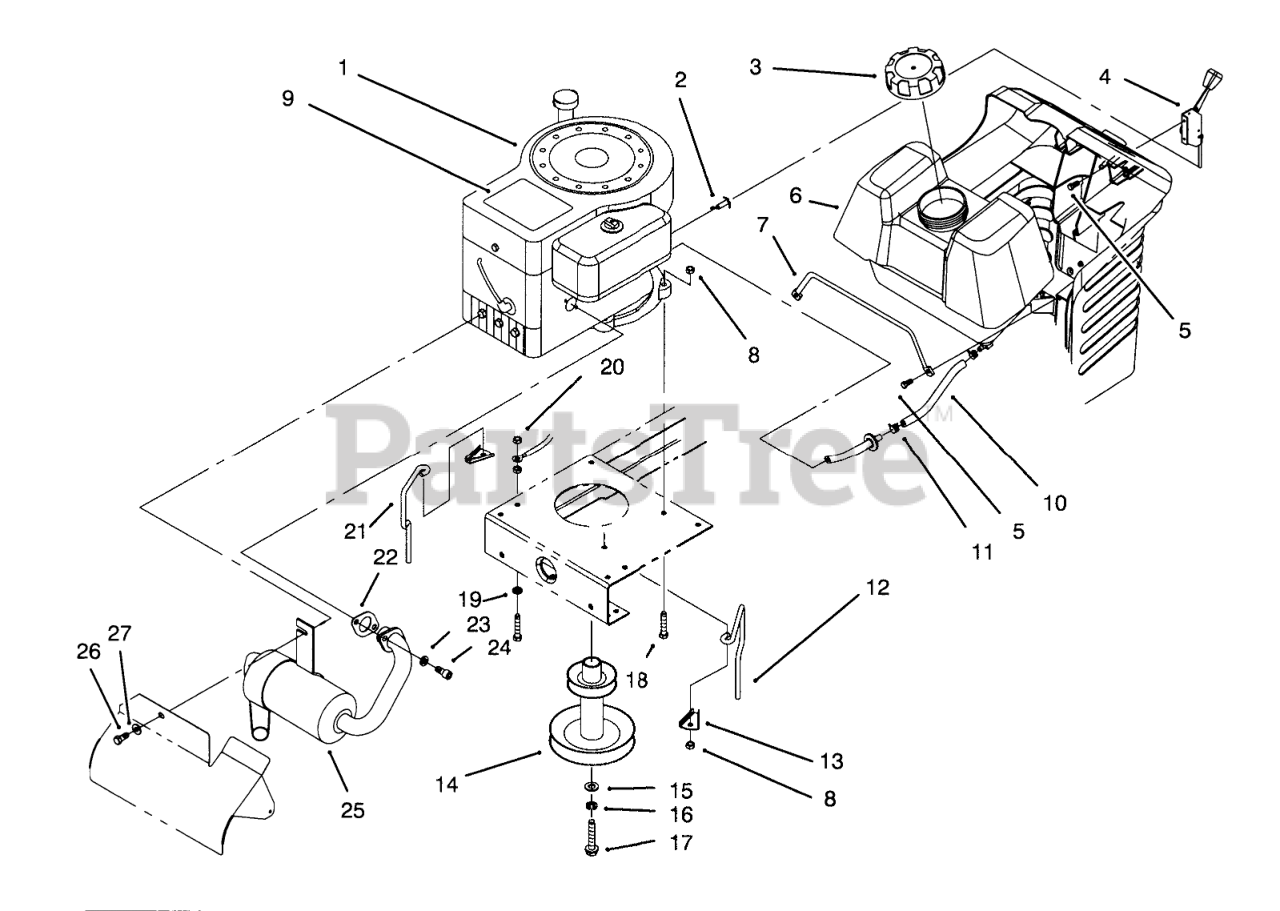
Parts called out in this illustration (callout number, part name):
1	Engine-12.5 H.P.
2	THROTTLE CABLE ASM
3	GAS CAP ASM
4	THROTTLE CONTROL ASM
5	SCREW-SPECIAL
6	GAS TANK ASM
7	GAS TANK ROD
8	NUT-LOCK, NI
9	DECAL - TORO QUIET 12.5
10	HOSE-FUEL
11	CLAMP-HOSE
12	LH BELT GUIDE
13	ANCHOR-GUIDE, BELT
14	ENGINE PULLEY
15	WASHER-FLAT
16	WASHER-LOCK
17	SCREW-HH
18	SCREW-HH
19	WASHER-LOCK
20	NUT-KEPS
21	RH BELT GUIDE
22	GASKET-EXHAUST
23	WASHER-LOCK
24	SCREW-HSH
25	MUFFLER
26	SCREW-HH
27	WASHER-LOCK
